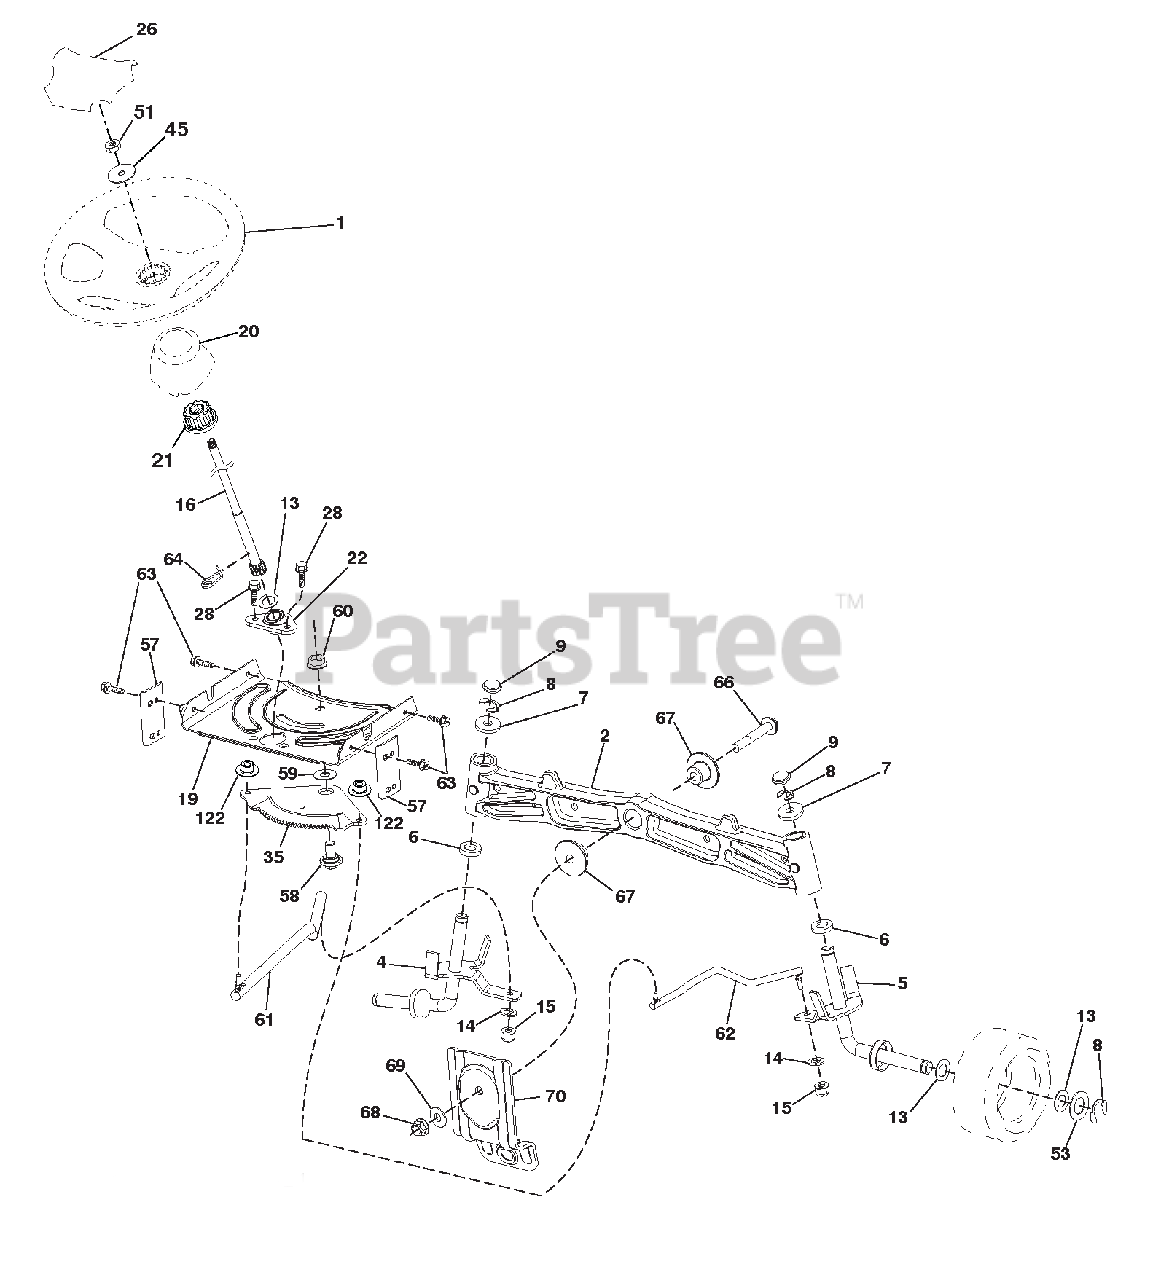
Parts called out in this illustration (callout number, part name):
1	WHEEL STEERING
2	AXLE.CAST IRON
4	SPINDLE.WELDED.LH.15"TEX
5	SPINDLE.WELDED.RH.15"TEX
6	WAHSER THRUST .75 X 1.230
7	WASHER.25/32 X 1-5/8 X 16GA.
8	RING.KLIP.#T5304-75
9	CAP.SPINDLE.FR.TOP.BLK.
13	WASHER.25/32 X 1 1/4 X 16 GA.
14	Washer, Lock 3/8
15	NUT.CROWNLOCK.3/8-24
16	SHAFT.STEER.3/4 TEX.NON-PLATED
19	PLATE.STEER.DDL.NLT/NGT
20	BOOT.STEERING
21	ADAPTER.WHEEL.STRG..760
22	STEERING SUPT.LOWER
26	CAP WHEEL STEERING HRS/SRS BLK
28	SCREW.HEXWSH THDR3/8-16X3/4.BL
35	GEAR SECTOR.PLATE.DDL.NLT/NGT
45	WASHER.9/16ID X 2-3/8OD.12GZIN
51	NUT.HEX.JAM.TOPLOCK.1/2-20 UNF
53	WASHER.HARDEN..793 X 1.637X060
57	BRACKET.UPSTOP.TEX
58	BOLT.SHOULDER.SECTOR.PIVOT.CFM
59	WASHER.THRUST.SECTOR.STEER.NLT
60	NUT.FLANGE LOCK.5/8-11
61	DRAGLINK.LH.BALLSTUD.DDL.
62	DRAGLINK.RH.BALLSTUD.DDL
63	SCREW.5/16-18X3/4.SMGML.TAP/BL
64	RETAINER.CLIP.SPRING.STEERING
66	BOLT.HEX.FGHD.7/16-14 X 3.SERR
67	BUSHING.PM.FRONT AXLE
68	NUT.LOCK.FLANGE.7/16-14.GR5
69	WASHER.1.5 X .505 X .118
70	BRACKET.DECK.SUSPENSION.FRONT
122	CAP GEAR SECTOR
